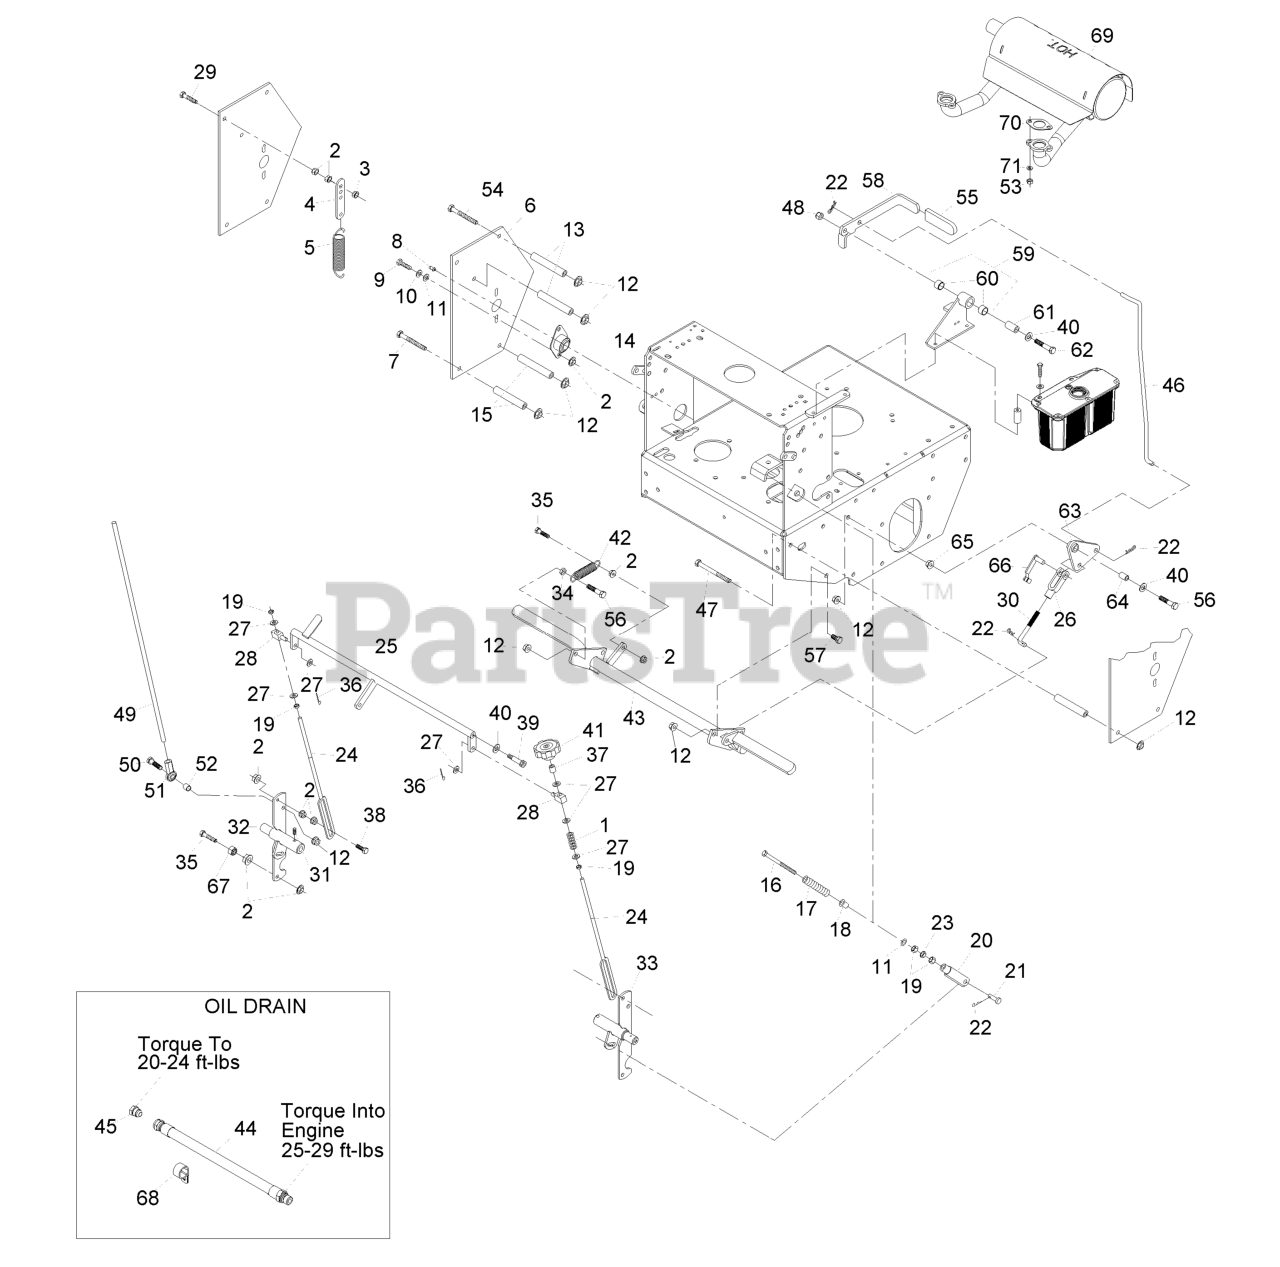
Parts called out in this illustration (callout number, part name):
1	SPRING-COMPRESSION
3	NUT-LOCK, NI
4	TAB-SPRING, EXTENSION
5	SPRING-EXTENSION
6	SHIELD-CONTROL
7	SCREW-HH
8	FITTING-GREASE
9	SCREW-HH
10	WASHER-LOCK
11	WASHER-FLAT
12	NUT-HHF, WHIZ
13	SPACER-SHIELD
14	BEARING-FLANGE, SIDE
15	SPACER-SHIELD
16	BOLT-RETURN, NEUTRAL
17	SPRING,COMPRESSION (NEUT)
18	BUSHING-FLANGED
19	NUT-HEX
20	YOKE-ADJUSTABLE
21	PIN-CLEVIS
22	PIN-COTTER
23	NUT-JAM
24	LINK-CONTROL, SPEED
25	CRANK-CONTROL, SPEED
26	YOKE-LINKAGE, BRAKE
27	WASHER-PLAIN
29	BOLT-TAP, HH
30	LINKAGE-LOWER
31	SCREW-SET
32	SHAFT-CONTROL, LH
33	SHAFT-CONTROL, RH
34	NUT-JAM
35	SCREW-HH, SPECIAL
36	PIN-COTTER
38	SCREW-HH
39	SCREW-HSH
40	WASHER-FLAT
41	KNOB-TRACKING
42	SPRING-IDLER
46	LINKAGE,UPPER- TTHP
47	SCREW-HH
48	NUT-LOCK, NI
49	LINK,DRIVE (PLTD)
50	SCREW-HH
51	JOINT-BALL END, LH
52	SPACER-TUBE, PUMP LINK
54	SCREW-HH
55	GRIP-LEVER
56	SCREW-HH
57	SCREW-HH
58	LEVER,PARK BRK W/DECAL
59	BRACKET ASM
60	SLEEVE-BUSHING
61	BUSHING-PIVOT
62	SCREW-HH
63	BELLCRANK ASM
64	BUSHING-PLASTIC
66	PIN-SPRING, CLEVIS
67	NUT-JAM
68	CLIP-LOOM
69	MUFFLER,HORIZONTAL
70	GASKET-EXHAUST
71	WASHER-LOCK
